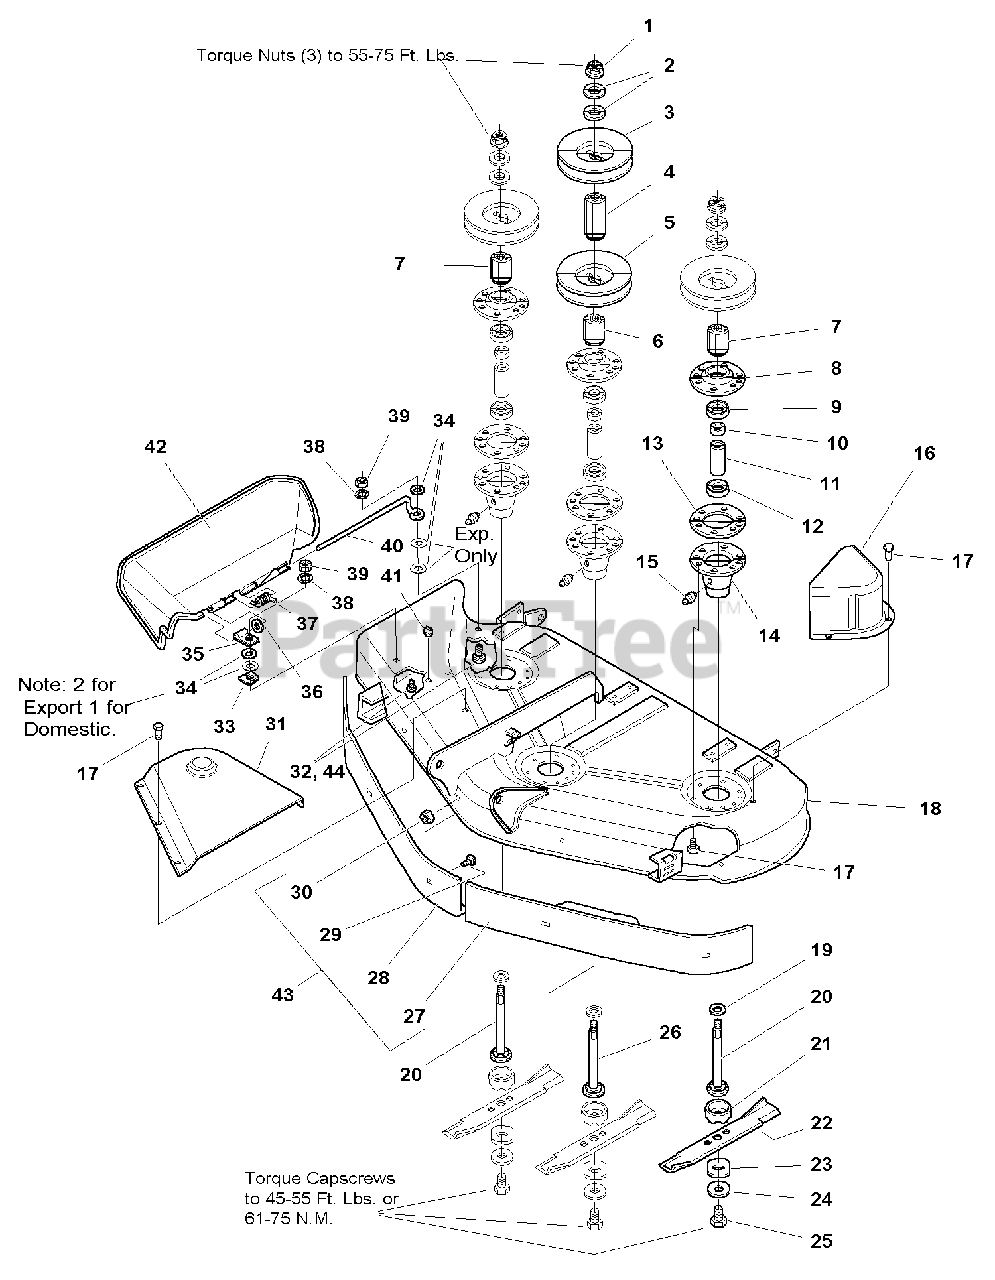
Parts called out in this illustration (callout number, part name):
1	NUT, Hex Flange, 9/16-18
2	WASHER, Belleville
4	HUB, Pulley, Double
6	HUB, Pulley, Double
7	HUB, Pulley
8	HOUSING, Arbor, Top
10	SPACER, Bearing Sleeve
13	GASKET, Foam
14	HOUSING ASSEMBLY, Arbor Bottom, w/Lube Fitting
15	FITTING, Lube
16	COVER, Arbor, Plastic
17	CAPSCREW, Hex Washer Head, Taptite, 5/16-18 x 3/4
18	HOUSING ASSEMBLY, 44" Orange
18	HOUSING ASSEMBLY, 44" Red
18	HOUSING ASSEMBLY, 44" Charcoal Grey
20	SHAFT, Arbor
21	SHIELD, Grass, Lower
22	BLADE, Mower, 16-1/8
22	BLADE, Mower, 50" Deck
23	WASHER, Hex
24	WASHER, Spring
25	CAPSCREW, Hex Head, 7/16-14 x 1-1/4
26	SHAFT, Arbor, Center
27	BAFFLE, Anti-Blowout, LH, 44" Deck
28	BAFFLE, Anti-Blowout, RH, 44" Deck
29	CARRIAGE BOLT, 5/16-18 x 5/8
30	NUT, Hex Flange, 2-Way Lock, 5/16-18
31	COVER, Arbor
32	CARRIAGE BOLT, 1/4-20 x 7/8 (Domestic)
33	NUT, Push On
34	WASHER, (3 for Domestic)
36	WASHER, 5/16
39	NUT, Hex, 1/4-20 ESNA
40	ROD, Deflector, Front
42	DEFLECTOR, Plastic
43	ANTI-BLOWOUT KIT, 44"
44	CARRIAGE BOLT, 1/4-20 x 1-1/4 (Export)
